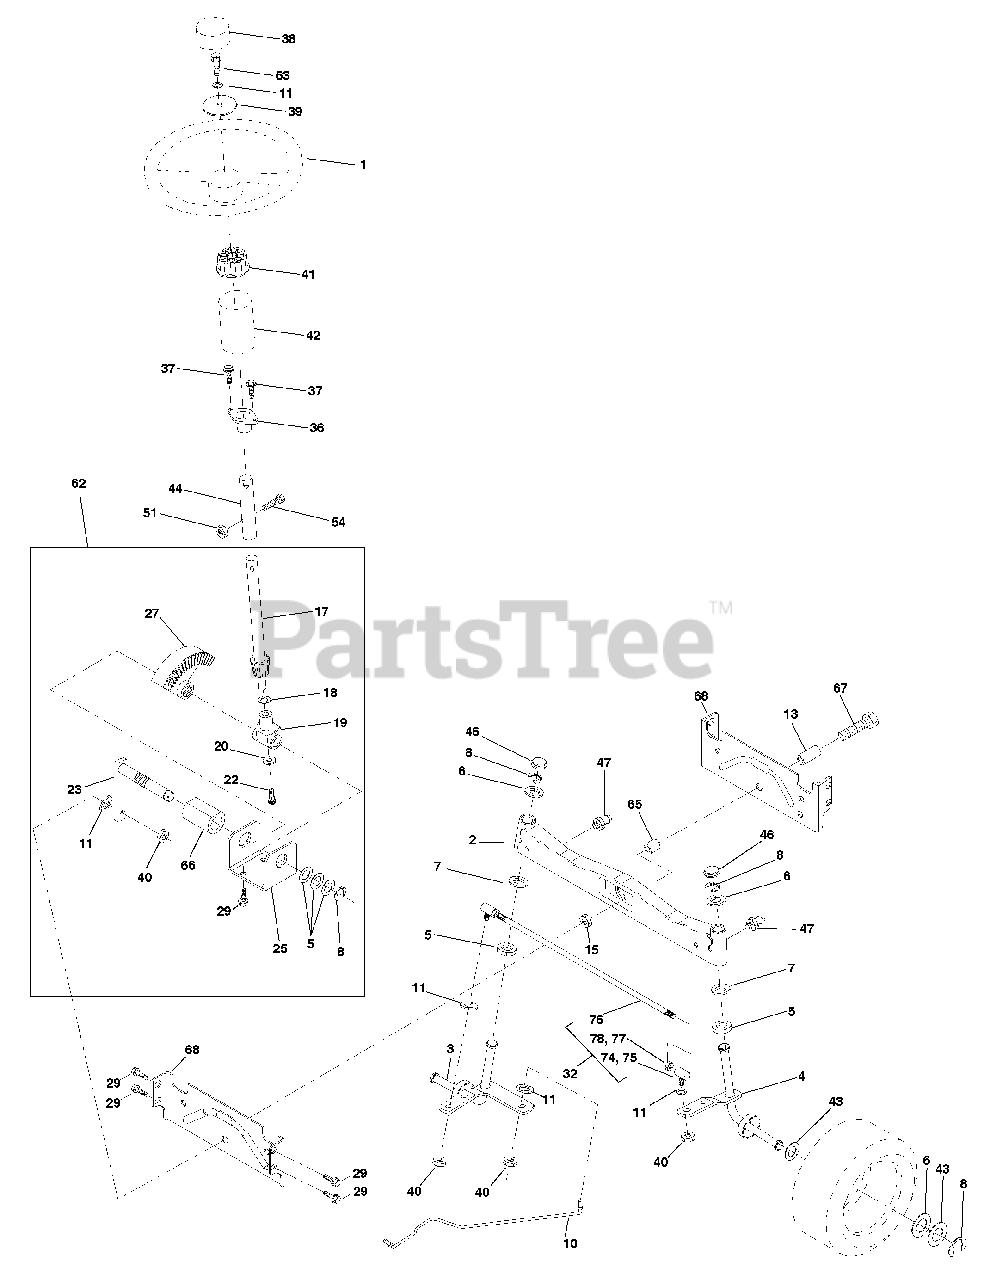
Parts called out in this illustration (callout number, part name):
1	Wheel Steering
2	Axle Front Casting Machined
3	Spindle Asm LH Cast 15"
4	Spindle Asm RH Cast 15"
5	Bearing Race Thrust Harden
6	Washer 25/32 X 1-5/8 X 16 Ga
7	Washer 27/32 X 1-1/4 X 16 Ga
8	Ring Klip #t5304-75
9	Bearing Col Strg Blk
10	Link Drag Extended Cast
11	Washer Lock Hvy Hlcl Spr 3/8
13	Bearing Axle STLT/GT
15	Nut Lock Flange 5/8-11 Unc
17	Shaft Asm Strg
18	Washer Thrust 515x 750x 033
19	Support Shaft
20	Washer Shim 1/4 X 5/8 X 062
22	Screw Hex Socket 1/4-20 x 5/8
23	Shaft Asm Pittman
25	Bracket Steering
27	Gear Sector
29	Screw Thdrol 3/8-16x3/4 Ty-tt
32	Rod Asm Tie Ball J Adj VGT
36	Bushing Strg
38	Insert Cap Strg Wh Au
39	Washer 13/32 X 2-3/8 X 8 Ga
40	Lock nut
41	Adaptor Wheel Strg
42	Boot Steering Shaft
43	Washer 25/32 X 1 1/4 X 16 Ga
44	Extension Steering Shaft LR/LT
46	Cap Spindle Fr Top Blk
47	Fitting Grease
51	Nut Lock Hex w/Ins 5/16-18
54	Bolt Fin Hex 5/16-18 Unc x 1-1/4
62	Kit, Steering Assembly Svc
63	Bolt Fin Hex 3/8-16unc x 1 Gr. 5
65	Spacer Axle
66	Bearing Arm Pittman
67	Bolt, Fin Hex 5/8-11 UNC x 2-3/4
68	Axle, Brace
74	Joint Asm Ball Rh
75	Joint Asm Ball Lh
76	Rod Tie Ball J Adj
77	Nut Hex Jam 3/8-24 Unf Lh
78	Nut Hex Jam 3/8-24 Unf
